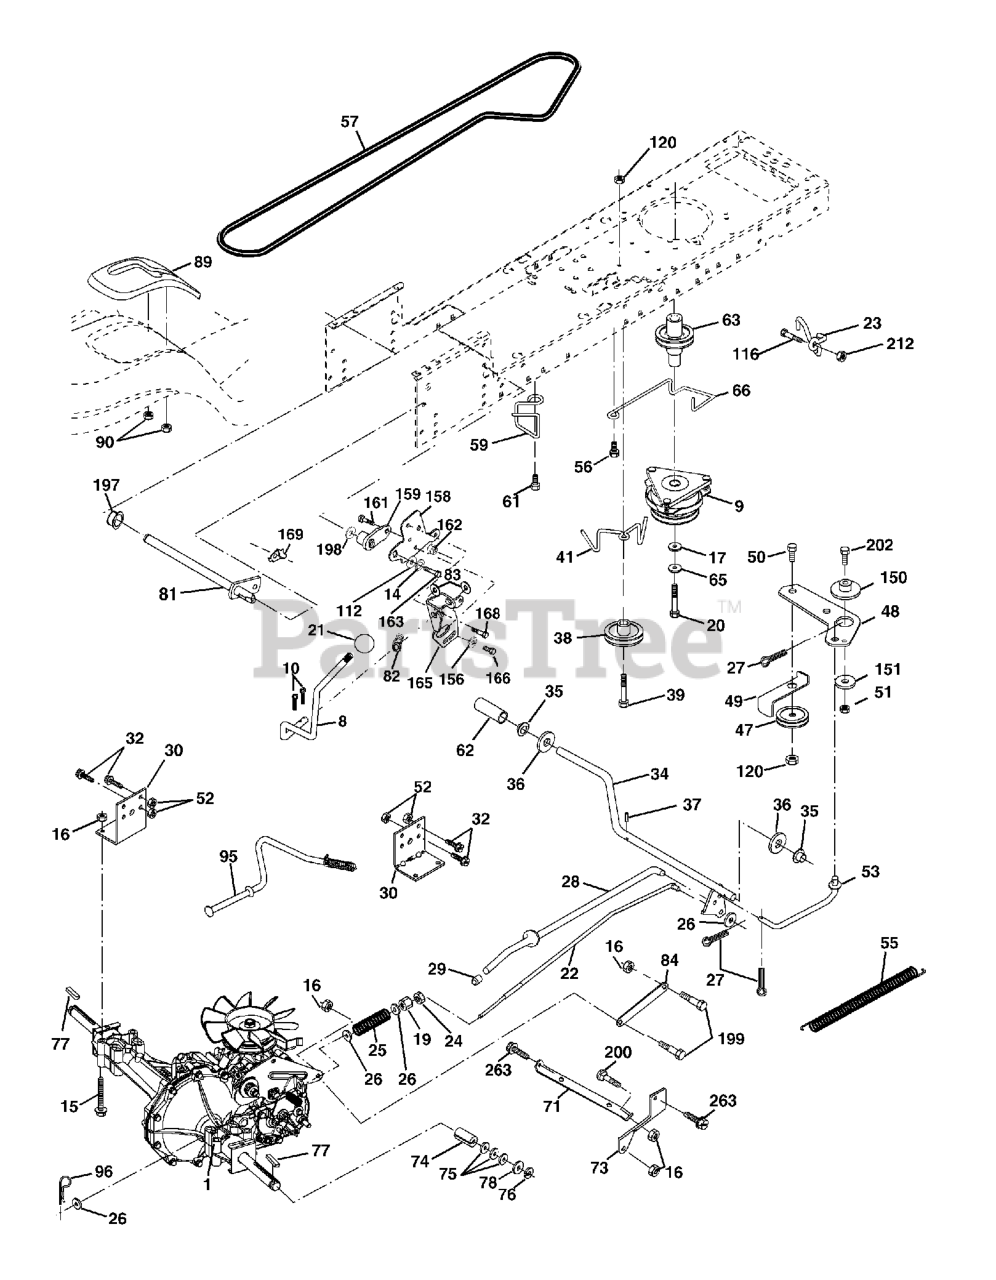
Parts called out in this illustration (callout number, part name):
8	ROD SHIFT FENDER ADJUST STLT
9	CLUTCH ELECTRIC
10	PIN COTTER
14	LOCKWASHER
15	BOLT HEX 5/16-18 GR 5
16	NUT.71038.31-18.HEX.NYLOCK
17	WASHER
19	NUT
20	BOLT HEX 7/16-20X4-1/4"
21	KNOB.DELUXE.(PISTOL.GRIP).BLAC
22	ROD BRAKE HYDRO
23	BRKT ASM MTNG
24	NUT
25	SPRING ROD LT
26	WASHER
27	COTTER PIN
28	ROD, PARKING BRAKE
29	PLUNGER CAP
30	BRKT, TRNSXLE MNT 20"
32	BOLT
34	SHAFT, FOOT PEDAL
35	BEARING.NYLON
36	WASHER LT
37	DRIVE PIN
38	PULLEY IDLER COMPOSITE
39	BOLT
41	KEEPER, BELT IDLER
47	IDLER PULLEY
48	BELLCRANK, CLUTCH
49	RETAIN BELT
50	BOLT.3/8-16X1.50
51	LOCKNUT
52	LOCKNUT
53	LINK, CLUTCH LT
55	SPRING, RETURN LT
56	SCREW.3/8-16
57	DRIVE BELT, LTH & YTH TRACTORS
59	KEEPER, BELT CENTER
61	SCREW 3/8-16X.875
62	PEDAL COVER T
63	PULLEY- ENGINE
65	LOCKWASHER
66	KEEPER BELT ENGINE
71	STRAP TORQUE LH HYDRO
73	STRAP TORQUE RH HYDRO
74	SPACER AXLE
75	WASHER
76	E-RING LT
77	SQUARE KEY
78	WASHER
81	SHAFT ASM CROSS TAPERED
82	SHIFT SPRING
83	WASHER
84	LINK TRANSAXLE
89	SHIFT CONSOLE
90	NUT.PUSH.3/16
95	CONTROL ASM. BYPASS HYDRO
96	RETAINER M
112	WASHER LT
116	BOLT D
120	NUT LOCK FLG 3/8-16 UNC
150	SPACER, RETAINER
151	WASHER 12/32X2X10GA
156	WASHER.SRRTD.5/16
158	BRACKET
159	RB HUB.SHIFT
161	BOLT
162	NUT.CROWNLOCK.1/4
163	BOLT
165	RP BRACKET
166	CAPSCREW.HXHD.FLG.5/16-18X.625
168	BOLT.SHOULDER.5/16-18X
169	PLATE.FASTENING.CROSS.SHAFT
197	NYLINER SNAP 5/8" ID
198	WASHER.NYL.7/8IDX.105"HYD CR
199	BOLT SHOULDER 5/16-18 UNC
200	BOLT
202	BOLT
212	NUT
263	SCREW, 3/8-16X3/4
